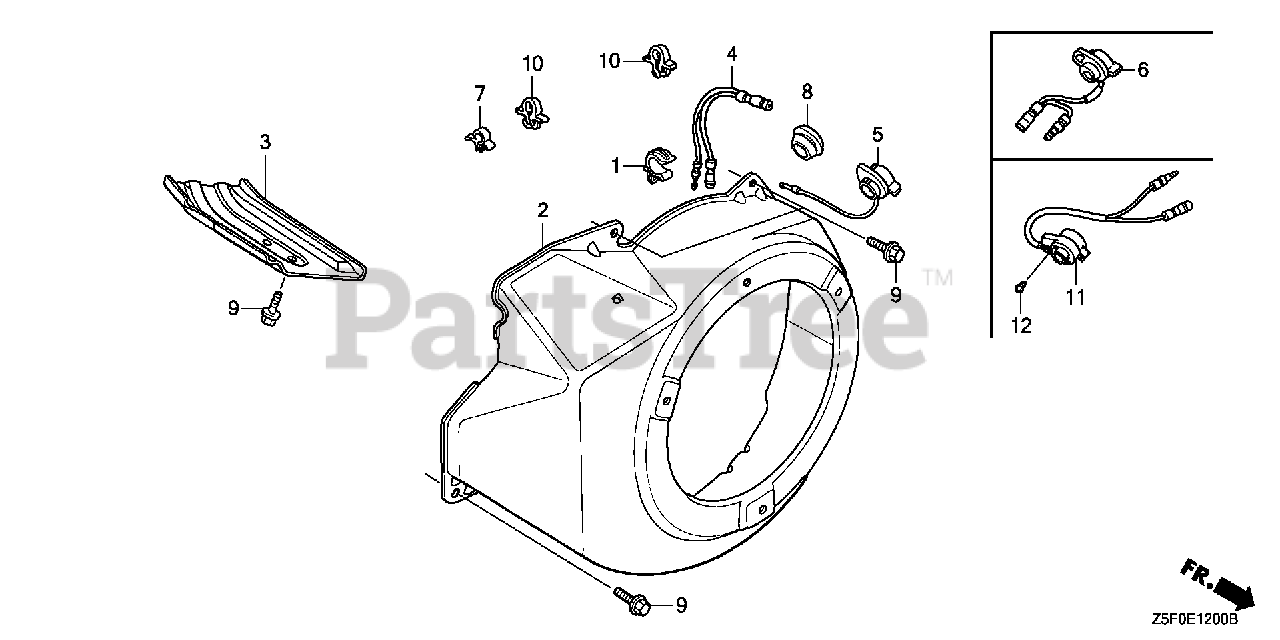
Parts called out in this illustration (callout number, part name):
1	CLIP, TUBE
2	COVER, FAN *NH1* (BLACK)
9	BOLT, FLANGE (6X12) (CT200)
11	SWITCH ASSY., ENGINE STOP
12	SCREW, TAPPING (3X6) (PO)
